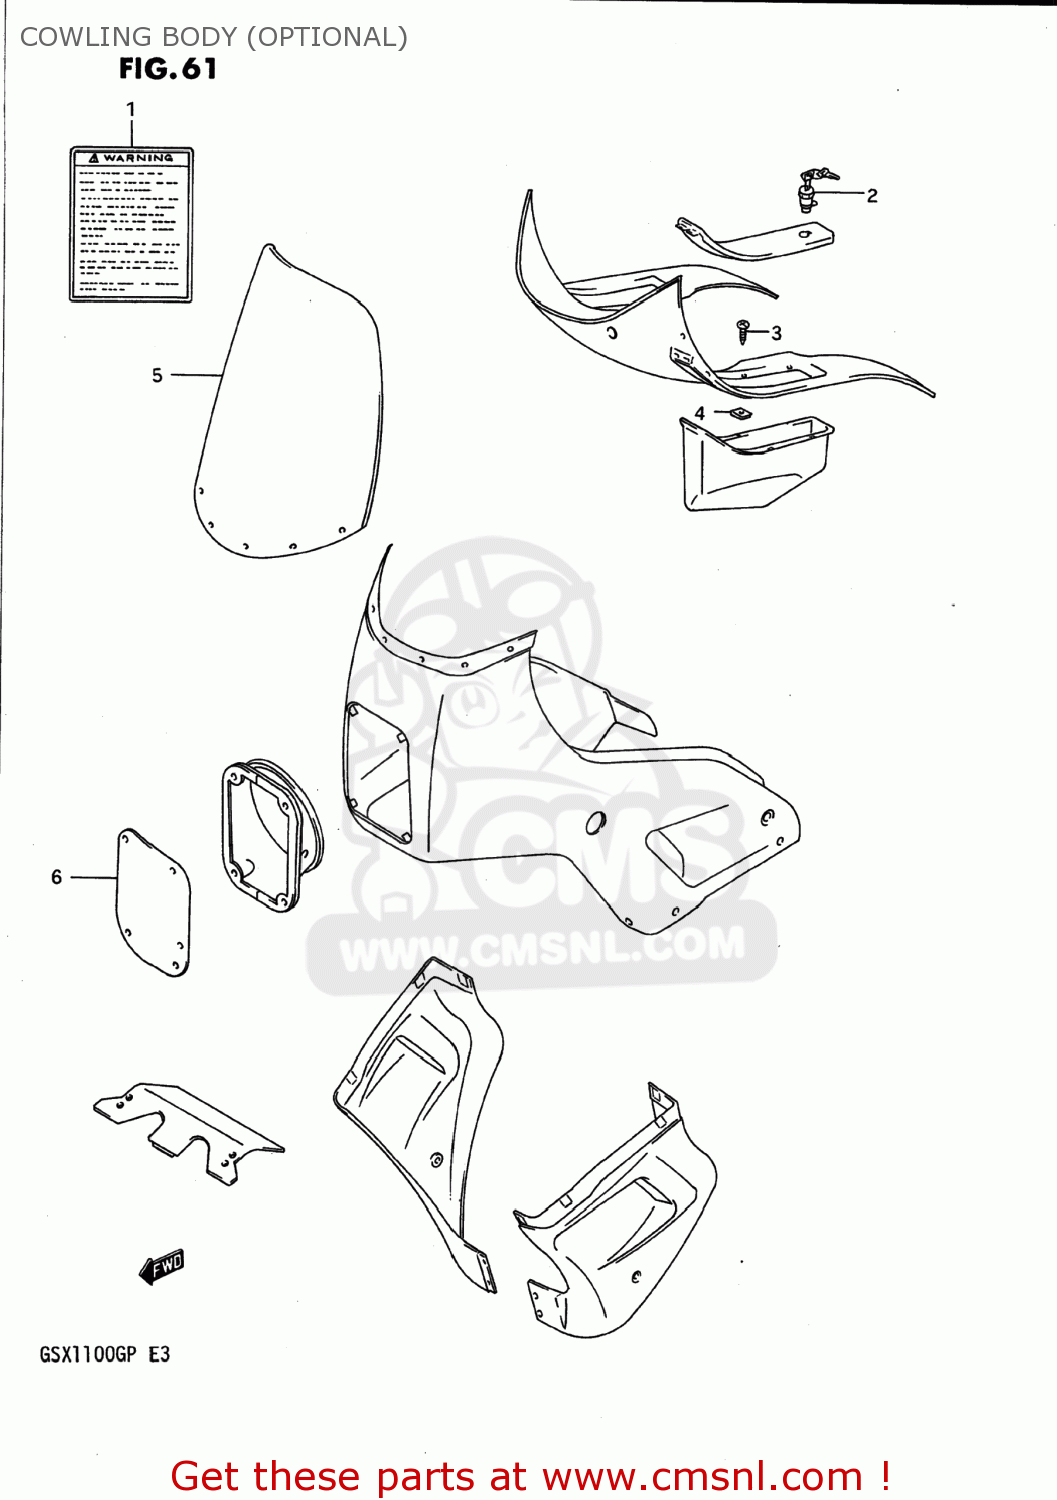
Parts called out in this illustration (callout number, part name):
1	LABEL (WARNING SCREEN)
2	LOCK SET,UPPER PANEL
3	SCREW
4	NUT
5	SCREEN,WIND
6	SCREEN,HEADLAMP
